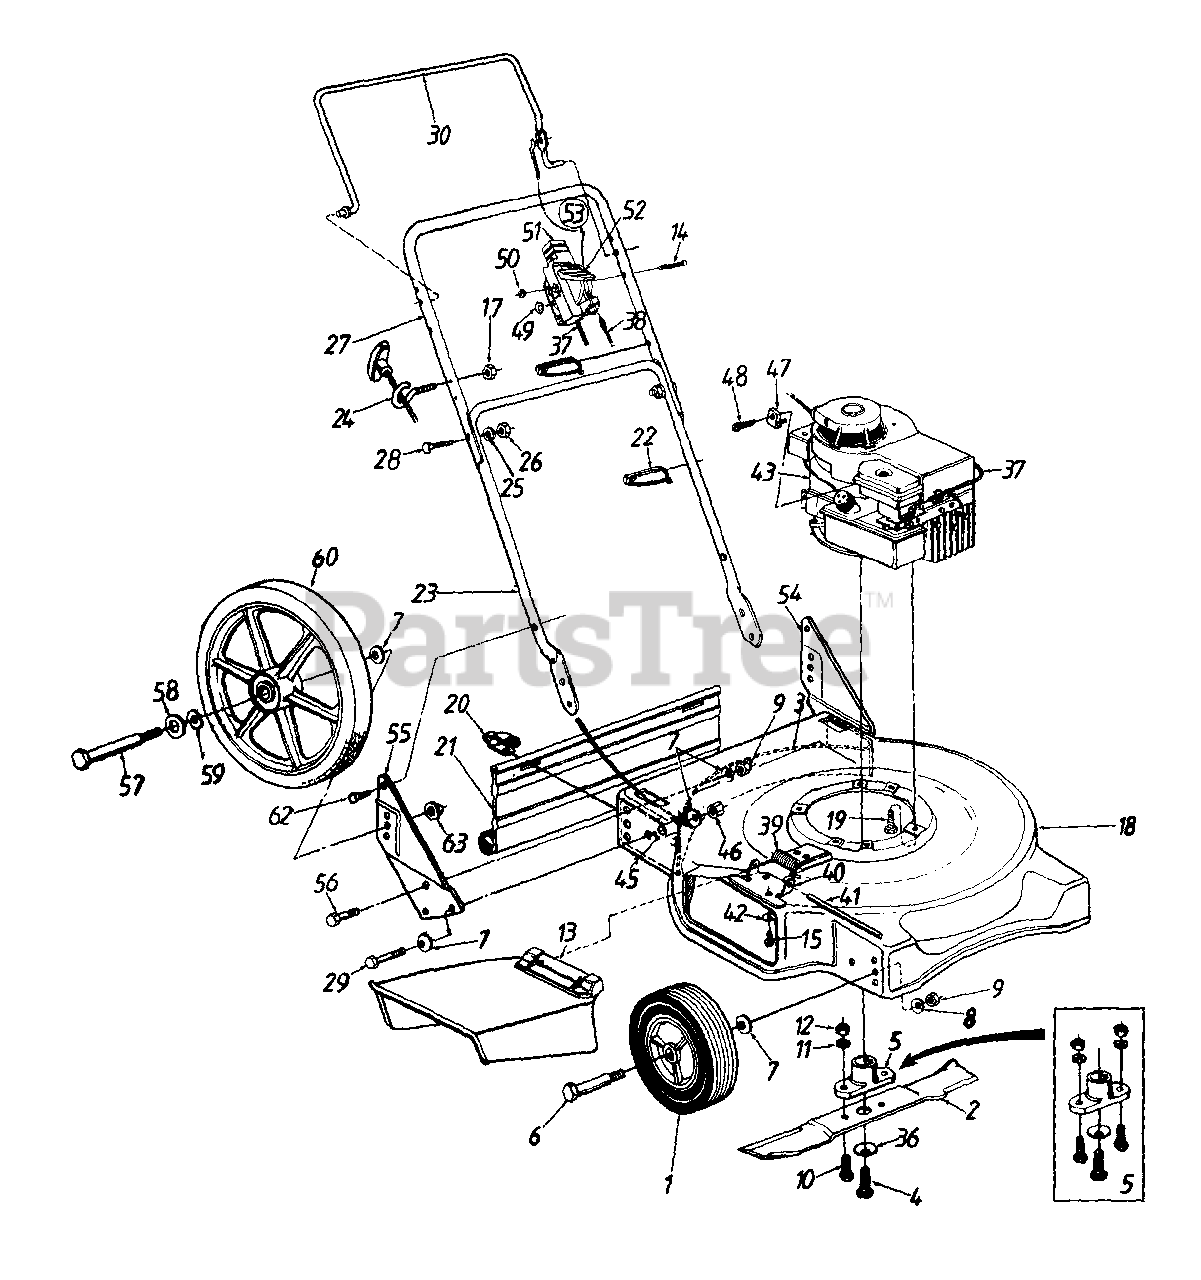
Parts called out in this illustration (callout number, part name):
1	Front Wheel Ass'y.
2	20" Blade
5	Blade Adapter Kit
6	Front Axle Bolt
7	Bell-Wash .380" I.D. x .88"
8	Bell-Wash .39" I.D. x 1.13"
9	Hex Nut 3/8-16 Thd.
10	Hex Bolt 3/8-24 x 1" Lg.
11	L-Wash. 3/8" I.D.
12	Hex Nut 3/8-24 Thd.
13	Chute Deflector Ass'y.
14	Oval C-Sunk Scr.
15	Self-Tap Scr. 1/4-20 x .5" Lg.
17	Hex L-Nut 1/4-20 Thd.
20	Hinge Clip
21	Rear Flap 16.62" Lg.
22	Cable Tie
23	Lower Handle
24	Rope Guide
25	L-Wash. 5/16" I.D.
26	Hex Nut 5/16-18 Thd.
29	Hex Bolt 3/8-24 x 1.5" Lg.
36	Bell-Wash .39" I.D.
37	Throttle Control Wire 51"
38	Control Cable - 36"
39	Torsion Spring
40	Adapter Plate
41	Hinge Pin
42	Bell-Wash. 1/4" I.D.
43	Engine
45	Spacer
46	Hex L-Nut 3/8-24 Thd.
47	Casing Clamp
48	Hex Wash. Hd. Scr. #10-32 x .62" Lg.
49	Spring Wash .66" I.D,
50	Hex L-Nut 1/4-20 Thd.
51	Throttle Body
52	Throttle Lever
53	Throttle Box Comp.
57	Rear Axle Bolt
58	Fl-Wash .51" I.D. x 1.37" O.D.
59	Spr. Wash .5" I.D. x 1" O.D.
60	Rear Wheel Ass'y.
62	Hex L-Wash. Hd. AB-Tap Scr. 1/4 x .62" Lg.
63	Flanged L-Nut 3/8-16 Thd.
